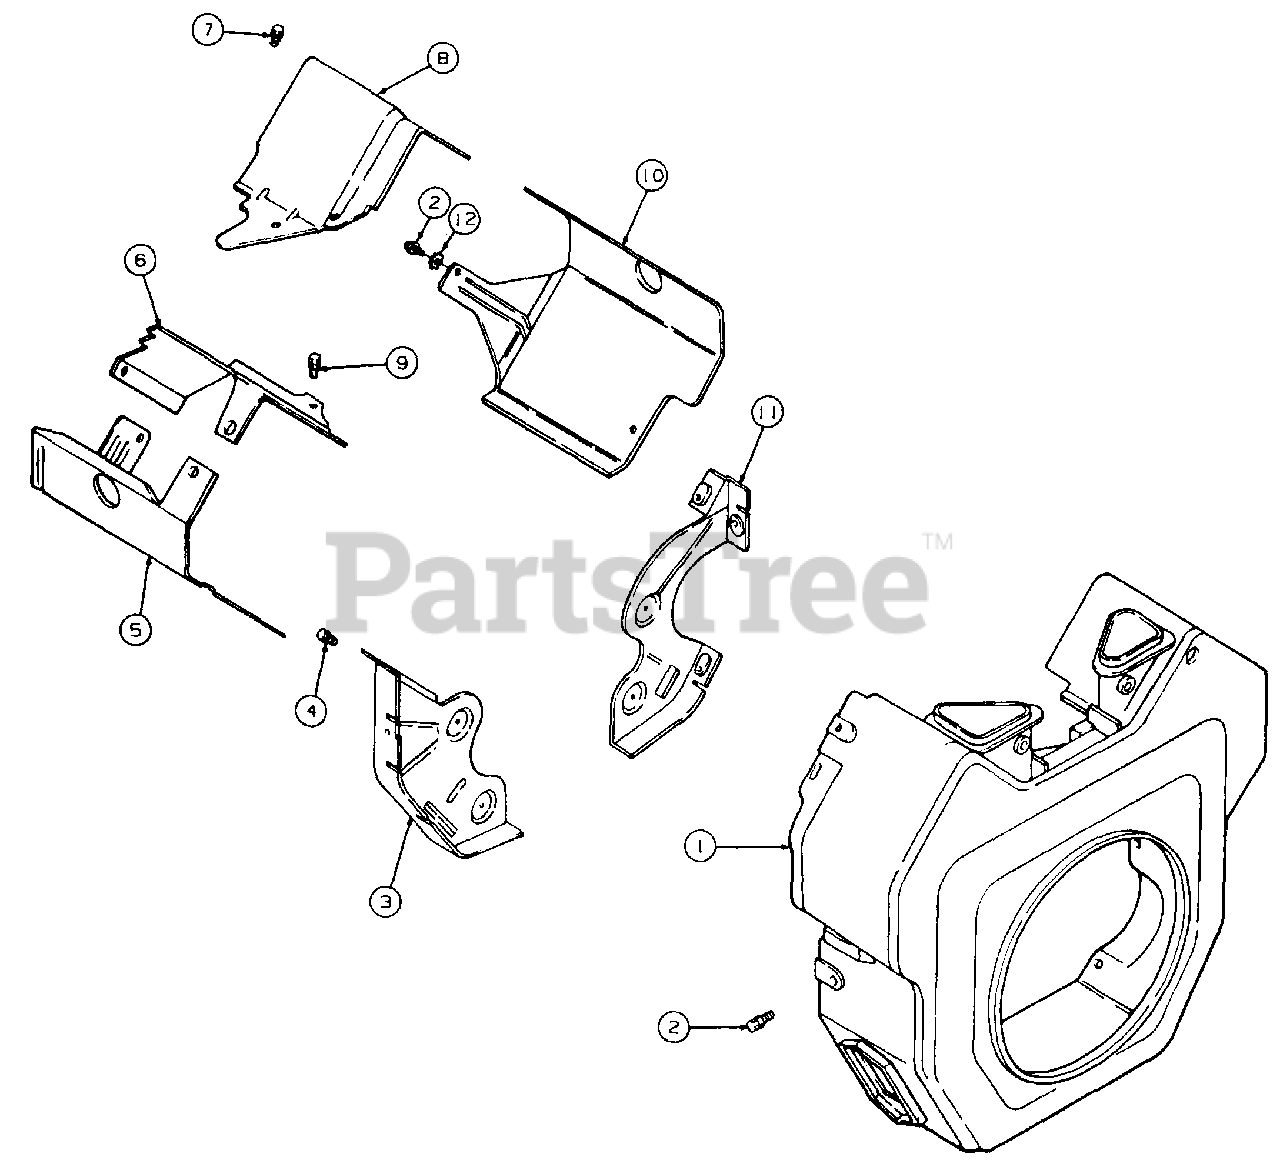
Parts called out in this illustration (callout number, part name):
1	Housing, Blower
2	Screw, M5 X 0.8 X 16
3	Plate, Backing #2
4	Screw, M6 X 1.0 X 16
5	Baffle, Cylinder Barrel #2
6	Baffle, Valley, #2
7	Screw, M5 X 0.8 X 10
8	Baffle, Valley #1
9	Screw, M6 X 1.0 X 16
10	Baffle, Cylinder Barrel #1
11	Plate, Backing #1
12	Washer, I.T./E.T., 1/4
